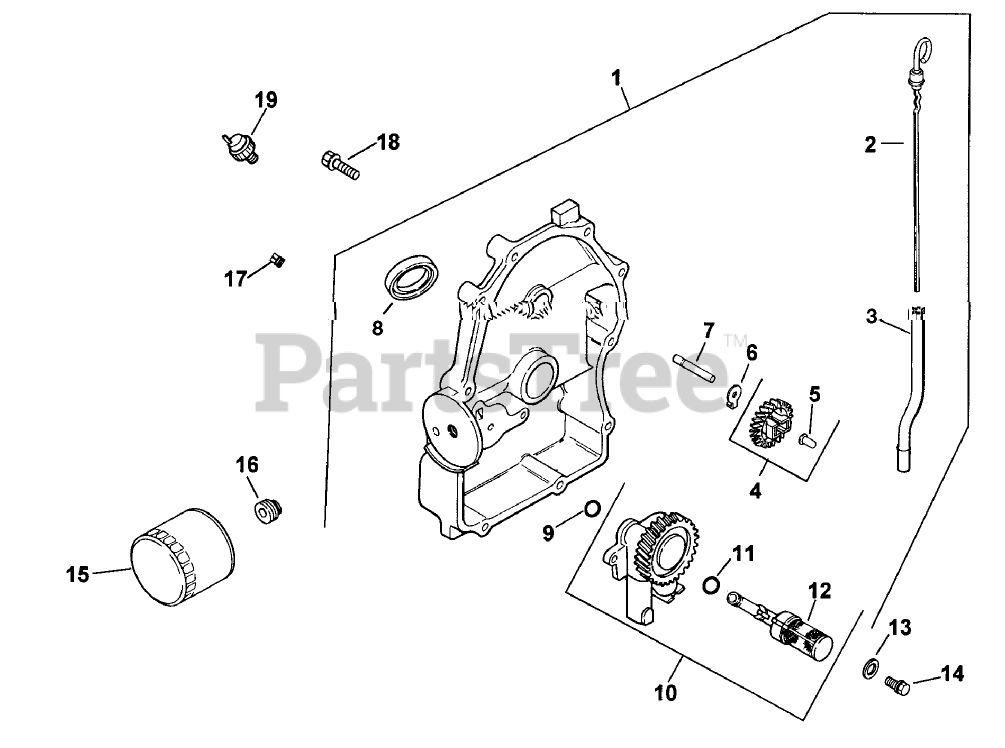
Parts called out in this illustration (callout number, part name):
1	Plate, closure Asm (Inc 2-12)
2	Dipstick
3	Tube-Dipstick
4	Kit, governor gear (Includes 5)
5	Pin-Governor
6	Tab-Locking
7	Shaft-Gear, Governor
8	Seal-Oil
9	O Ring
10	Oil pump Asm (Incl. 11-12)
11	O-Ring
12	Pick Up-Oil
13	Washer
14	Screw
15	Filter-Oil
16	Nipple-Filter, Oil
17	Plug
18	Screw
19	Switch, pressure
